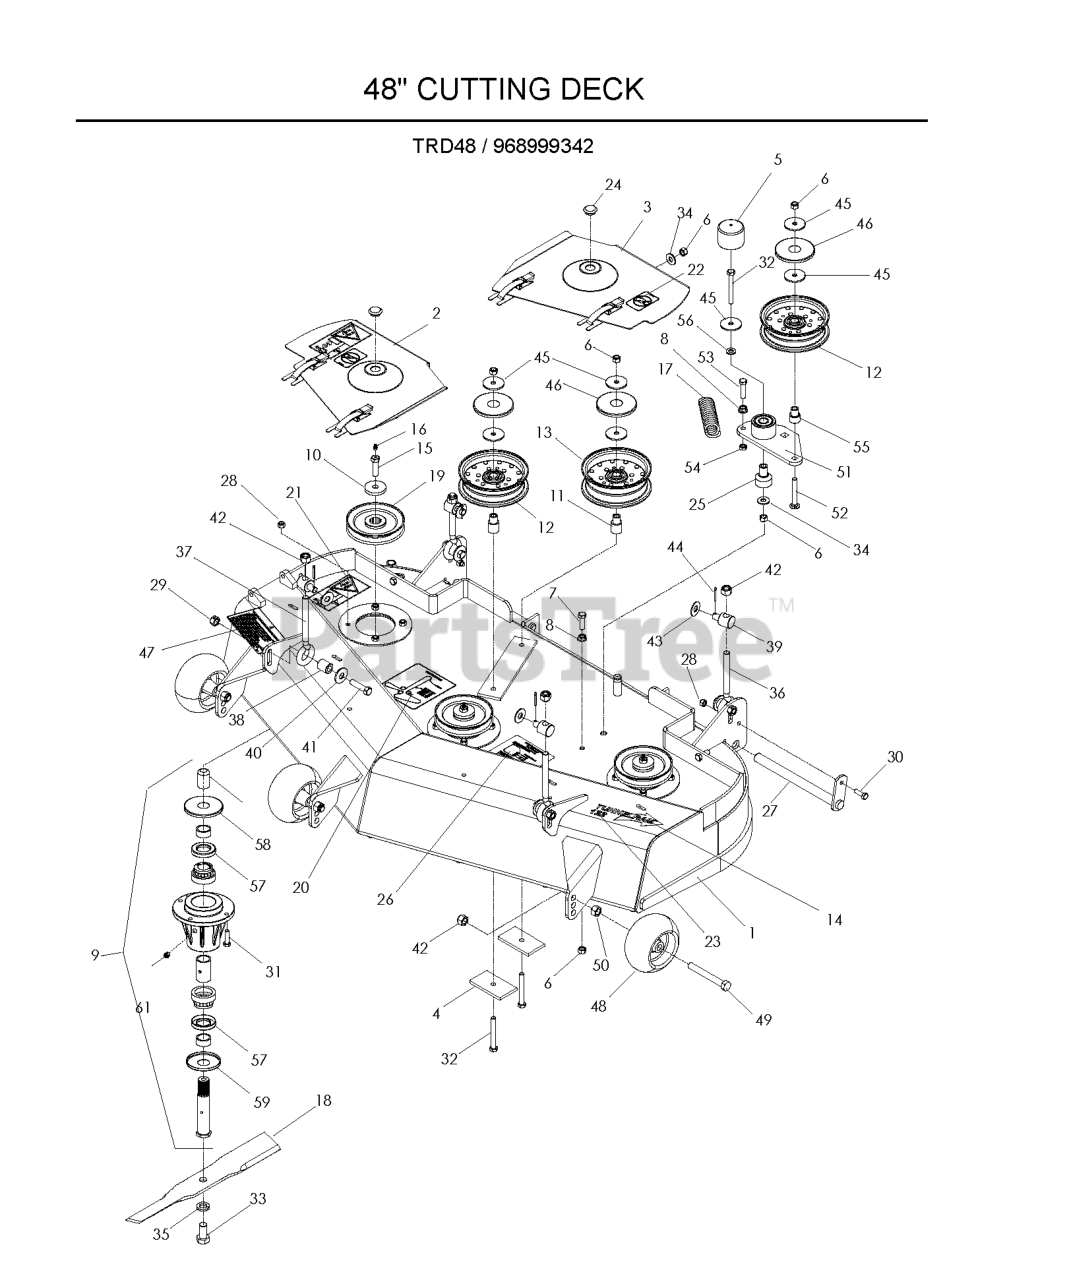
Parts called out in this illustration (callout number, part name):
1	DECK W/DECALS 48" HUS
2	BELT SHIELD ASSEMBLY, 48" R.H.
3	BELT SHIELD ASSEMBLY, 48" L.H.
4	SUPPORT PLATE
5	CAP, VINYL
6	NUT 3/8-16 NYLOC
7	HCS 3/8C X 1 1/4 GR5
8	NUT 3/8C WHIZ
9	HOUSING ASM, 52/61
10	SPINDLE WASHER
11	IDLER BUSHING
12	IDLER PULLEY
13	IDLER PULLEY (TALL)
14	DECAL, TUNNEL RAM 6"
15	HCS 7/16-20 GD 8 SPEC
16	ZERK
18	BLADE, 16-1/4"
19	PULLEY 42-48
20	DECAL, BELT ROUTING
21	DECAL, EURO SEVERING
22	DECAL, NO STEP
23	DECAL, 122
24	PLUG, BUTTON HOLE
25	PIVOT, BEARING
26	DECAL, ANTI SCALP
28	NUT 5/16 NYLOC
29	NUT 7/16C CENTERLOCK
30	HCS 5/16C X 1
31	HCS 5/16C X 1 1/4
32	HCS 3/8C X 3
33	HCS 5/8F X 1 1/4
34	WASHER 3/8 FLAT
35	LOCKWASHER 5/8
37	EYEBOLT, 1/2-13 X 5.88
40	SPRING WASHER - .50
41	HCS 7/16 - 14 X 1 3/4
42	NUT 1/2-13 HEX NYLOC ZD
43	WASHER 1/2 FLAT
44	PIN COTTER 1/8 X 1 ZD
45	WASHER, 3/8 SPEC
46	TOP DUST CAP
47	DECAL, DISCHARGE, MULTILINGUAL
48	GAUGE WHEEL
49	HHB, 1/2-13X4
50	NUT HEX 1/2
51	ARM-IDLER W/BRG
52	RHSNB 3/8-16 X 2.75
53	HCS 3/8-16 X 1-1/2
54	NUT 3/8-16 HEX JAM
55	BUSHING, IDLER
56	WASHER 3/8 SAE FLAT
57	SHAFT SEAL
58	TOP DUST CAP
59	BOTTOM DUST CAP
61	PLUG-VENTED
